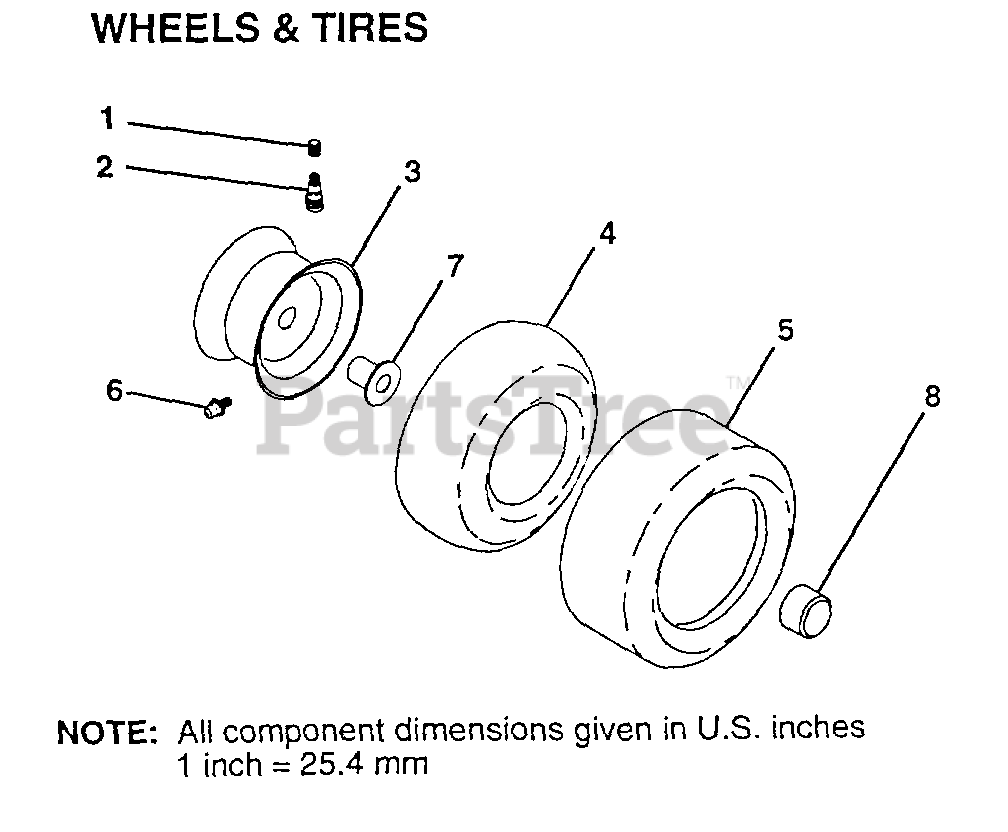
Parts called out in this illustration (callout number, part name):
1	VALVE CAP
2	VALVE STEM LT
3	RIM.FRONT.
4	TUBE.16X6.5/7.5-8
6	ZERK FITTING M
7	"FLANGE, BEARING"
8	HUB CAP
